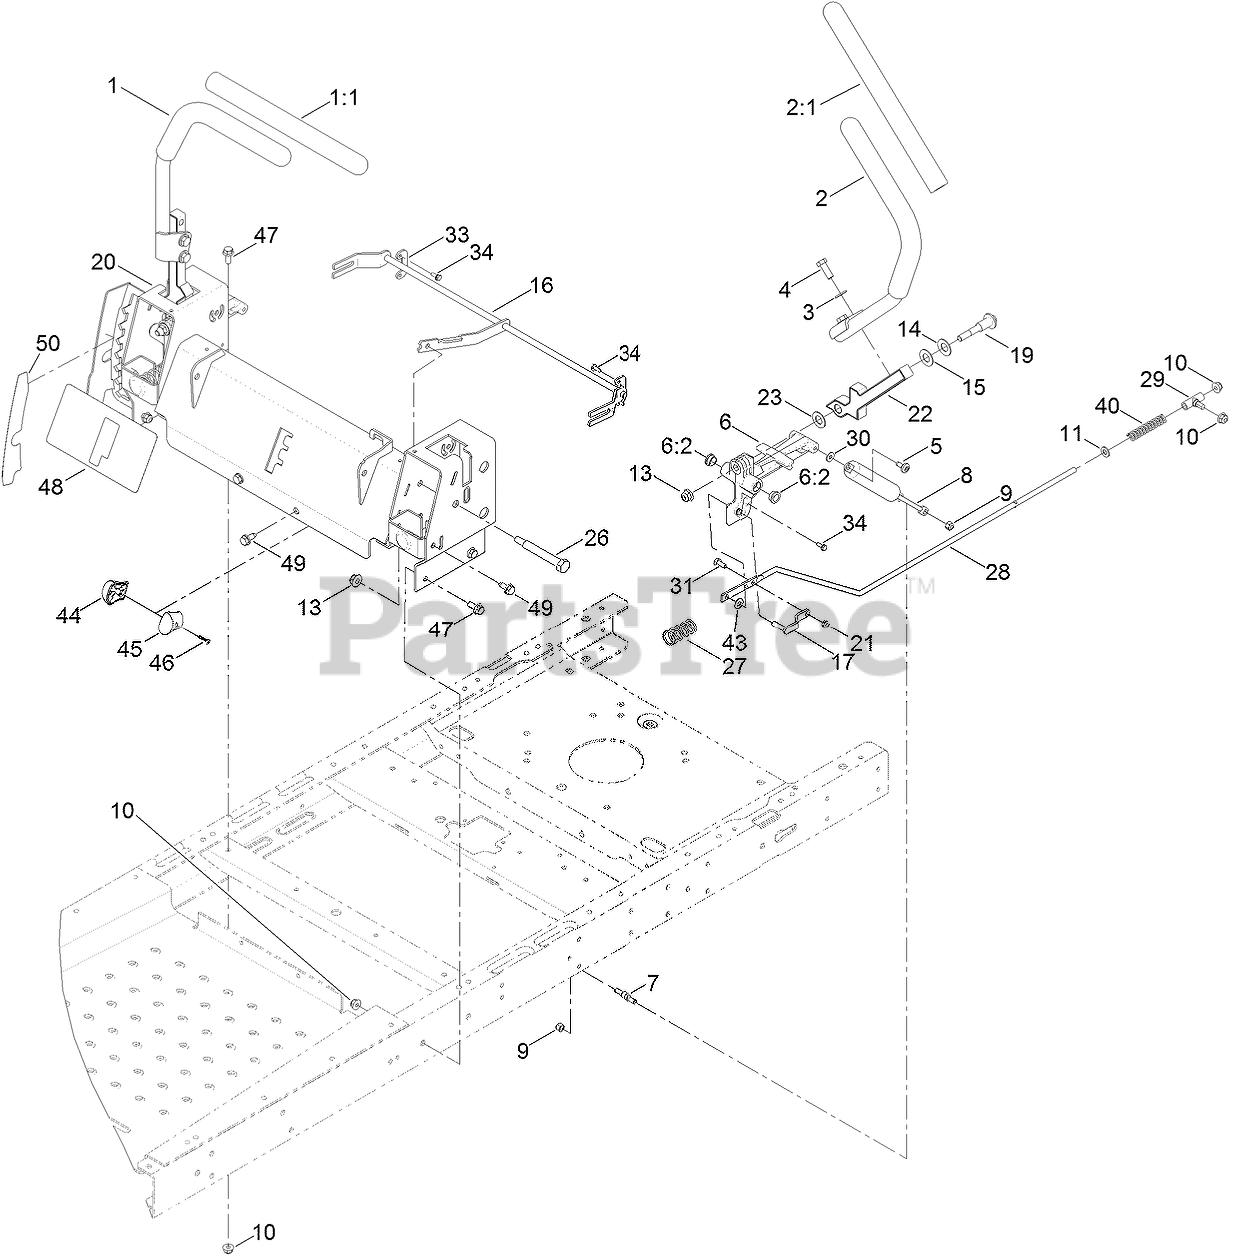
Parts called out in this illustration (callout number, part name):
1	HANDLE-CONTROL, RH
2	HANDLE-CONTROL, LH
3	WASHER-FLAT
4	SCREW-HH
5	SCREW-SHOULDER
6	ACTUATOR ARM ASM
6:2	BUSHING-FLANGE
7	STUD-DAMPER
8	DAMPER
9	NUT-LOCK, NI
10	NUT-HF, NI
11	WASHER-PLAIN
13	NUT-HF, NI
14	WASHER-BELLEVILLE
15	WASHER
16	SPEED CONTROL ASM
17	PIN-ROD, HYDRO
19	BOLT-PIVOT
20	CONTROL BOX ASM
21	NUT-LOCK, NI
22	LEVER-CONTROL
23	WASHER-NYLON
26	BOLT-PIVOT
27	SPRING-RETURN
28	ROD-HYDRO
29	MOUNT-ROD, HYDRO
30	WASHER
31	SCREW-HH
33	RETAINER
34	SCREW-TAPTITE
40	SPRING-RETURN, NEUTRAL
43	SPACER-NYLON
44	KNOB-RH
45	KNOB-LH
46	SCREW-PPH
47	SCREW-HHF
48	DECAL-CONTROL, SPEED
49	SCREW-HWHTF
50	DECAL-HOC
